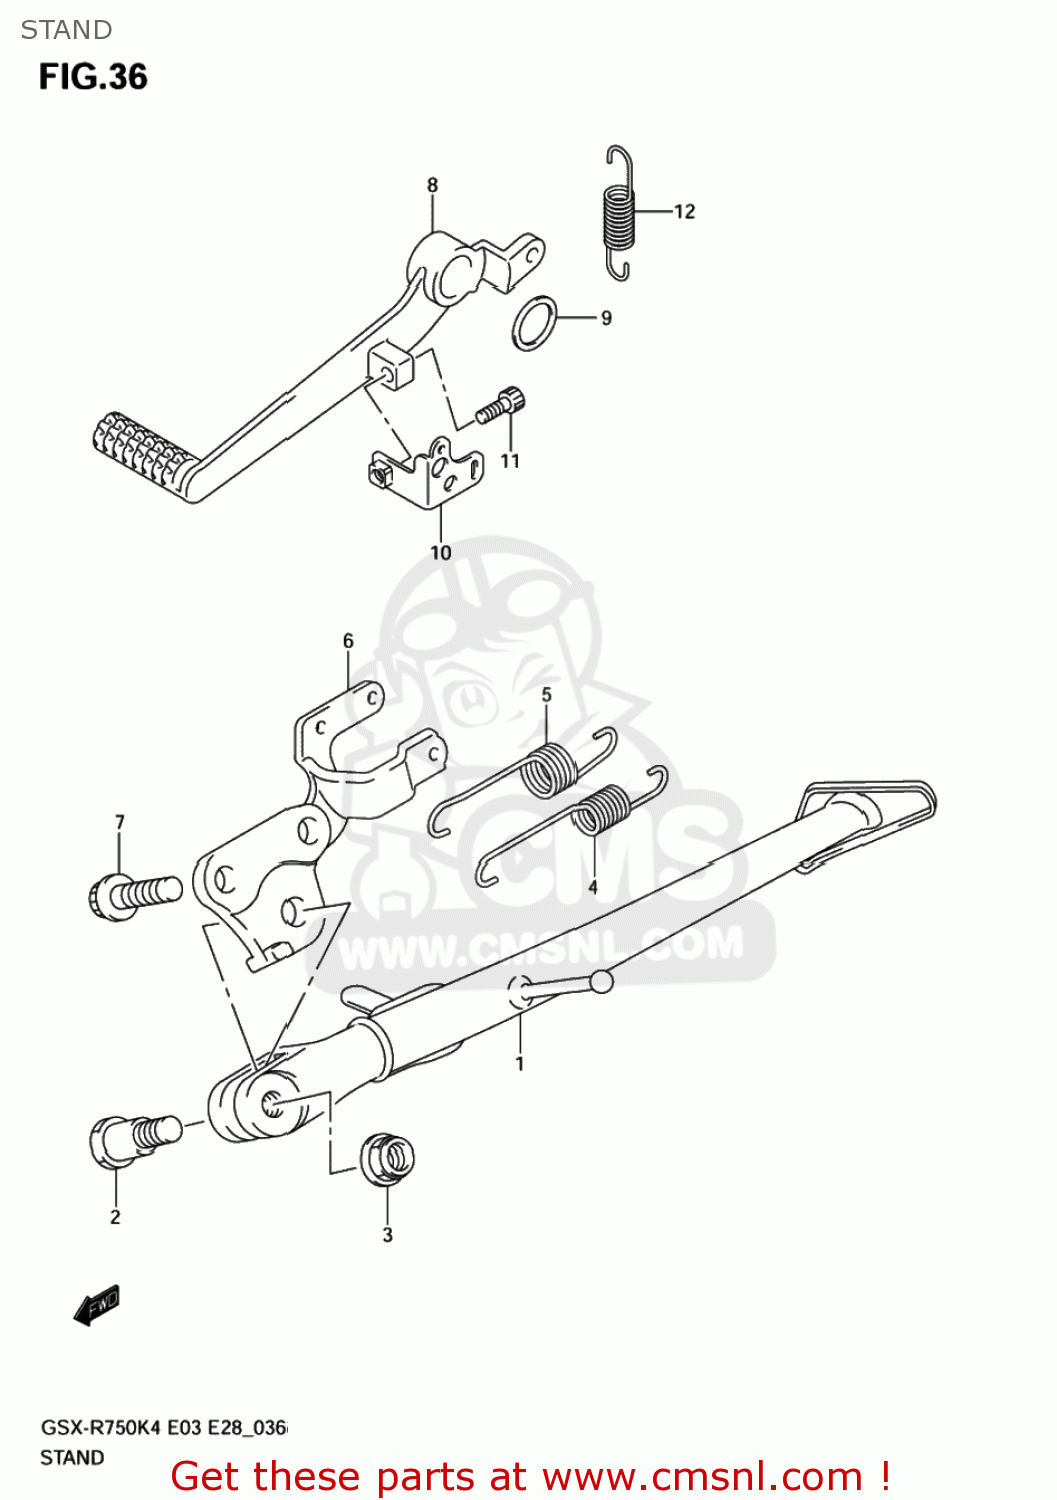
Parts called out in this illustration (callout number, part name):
1	STAND,PROP
2	BOLT(10X21)
3	NUT
4	SPRING
5	SPRING
6	BRACKET,PROP STAND
7	BOLT(10X28)
8	PEDAL,BRAKE
9	WASHER(18X24X1)
10	BRACKET,RETURN SPRING
11	BOLT,OIL FILLE
12	SPRING
